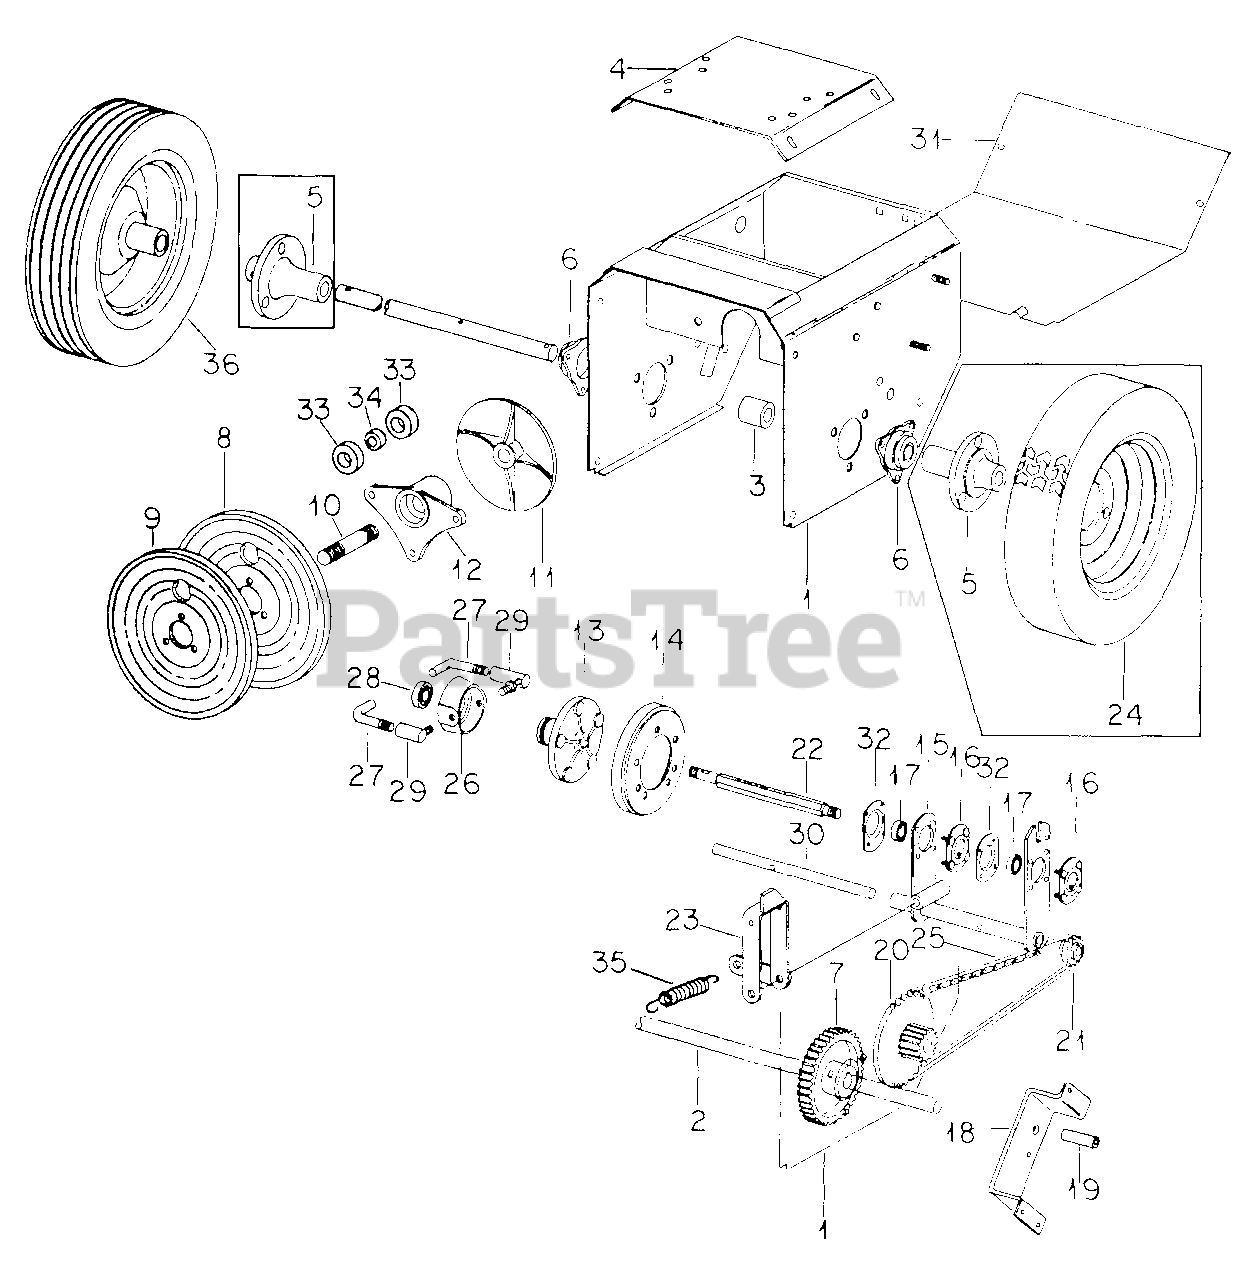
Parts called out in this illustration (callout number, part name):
1	HOUSING, MAIN DRIVE
2	AXLE
3	SPACER, AXLE
5	HUB, WHEEL
6	BEARING, FLANGE AXLE
7	GEAR, SPUR - 40 TEETH
10	SHAFT, DRIVEN
12	HOUSING, BEARING
13	HUB, DRIVEN DISC
14	WHEEL, FRICTION
15	BRACKET, DRIVE
16	RETAINER, BRG
17	BEARING, BALL
18	BRACKET, TRANSFER
20	SPROCKET, SPUR GEAR
21	SPROCKET - 9 TEETH
23	BRACKET, SHIFTING
24	WHEEL W/TIRE ASSY
25	CHAIN, ROLLER
28	BEARING, BALL
29	JOINT, 1/4-28 BALL
30	SHAFT, PIVOT
31	PLATE, BOTTOM GUARD
32	RETAINER, BEARING
33	BEARING, HOUSING BALL
34	SPACER, BEARING
35	SPRING, EXTENSION
36	WHEEL W/TIRE ASSY
IH-102581	SCREW, 5/16-18 X 3/8 HDLS HEX-SOC-HD CUP-PT SET
